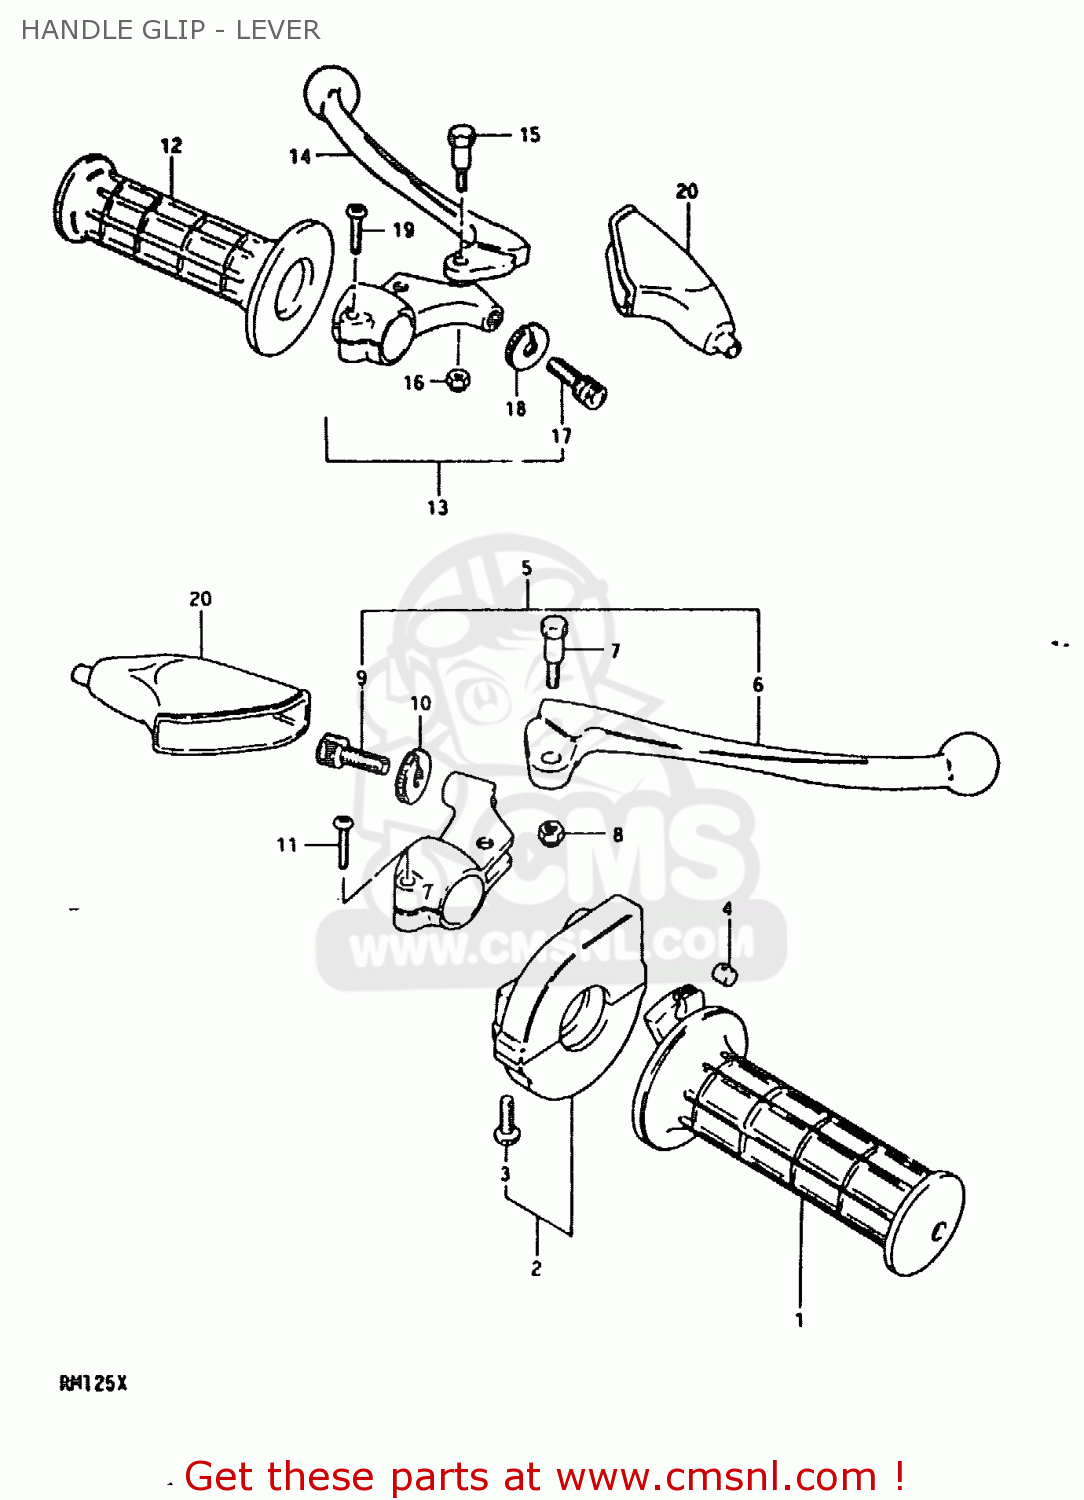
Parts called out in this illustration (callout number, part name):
1	GRIP,THROTTLE
2	CASE ASSEMBLY,THROTTLE
3	SCREW
4	PIECE,THROTTLE END
5	LEVER ASSEMBLY,BRAKE
6	LEVER,BRAKE
7	BOLT,LEVER
8	NUT 6MM
9	ADJUSTER,CABLE
10	NUT,CABLE ADJUSTER
11	SCREW
12	GRIP,LEFT
13	LEVER ASSEMBLY,CLUTCH
14	LEVER,CLUTCH
15	BOLT,LEVER
16	NUT 6MM
17	ADJUSTER,CABLE
18	NUT,CABLE ADJUSTER
19	SCREW
20	COVER,CLUTCH LEVER
